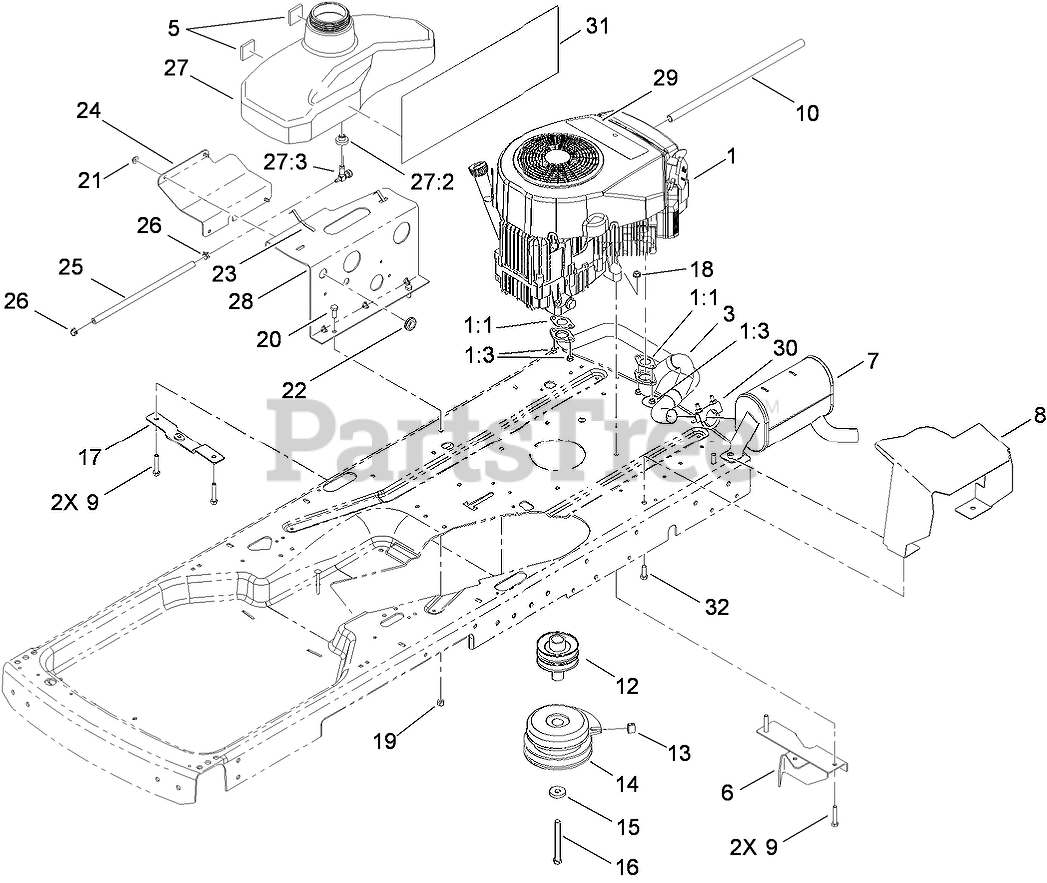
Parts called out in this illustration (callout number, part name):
1:1	GASKET-EXHAUST
1:3	NUT-M8
3	MANIFOLD
5	FOAM-SWITCH, SEAT
6	BRACKET-PIVOT
7	MUFFLER
8	SHIELD-MUFFLER
9	SCREW-HH
10	TUBE-DRAIN, OIL
12	PULLEY-ENGINE
13	BUMPER
14	CLUTCH-ELECTRIC
15	WASHER
16	SCREW-HH
17	PLATE-MOUNT, IDLER
18	NUT-HF
19	NUT-LOCK, NI
20	SCREW-HH
21	SCREW-HHFTF
22	GROMMET
23	SPRING
24	PLATE-SUPPORT
25	HOSE-FUEL
26	CLAMP-HOSE
27	GAS TANK ASM
27:2	BUSHING
27:3	VALVE-FUEL
28	PLATE-TANK
30	CLAMP-MUFFLER
31	FOIL-SHIELD, HEAT
32	SCREW-HH
